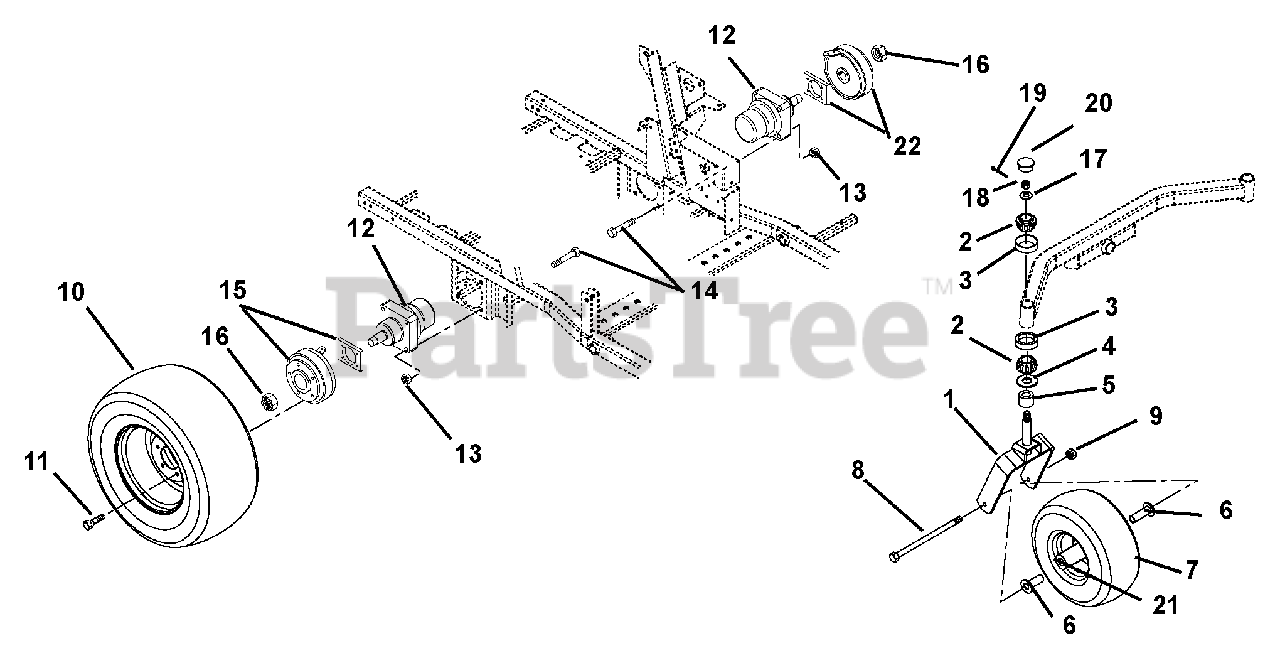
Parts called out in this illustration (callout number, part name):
1	Fork, Front
2	Bearing, Cone w/ Grease
3	Bearing, Cup 1.980 x .420
4	Bearing Seal 1.5 x 2 x .18
5	Spacer, PM, 1.03 I.D. x 1.5 O.D. x .375
6	Spacer, Wheel
7	Wheel/Tire Assembly
7	Tire, 15 x 6-6
8	Bolt, Hex .50-13 x 9.00 Grade 5
9	Nut, Locking Center .50-13
10	Tire/Wheel Assembly 24 x 12-12
10	Tire, Turfmaster 24 x 12-12
11	Bolt, Lug .50-20 x 1.38 Grade 8, 60 Degree
12	Hydraulic Wheel Motor
13	Nut, Locking Top Flange .50-13
14	Bolt, Wheel Motor .50-13 x 2.75
15	Brake, Right Hand Park
16	Nut , Lock Jam Patch
17	Washer, Flat Steel .755 x 1.375 x .062
18	Nut, Slotted .75-16
19	Pin, Cotter .16 x 1.00
20	Cap, Dust
21	Bearing, 25mm I.D. x 52mm OD x 15mm
22	Brake, Left Hand Park
